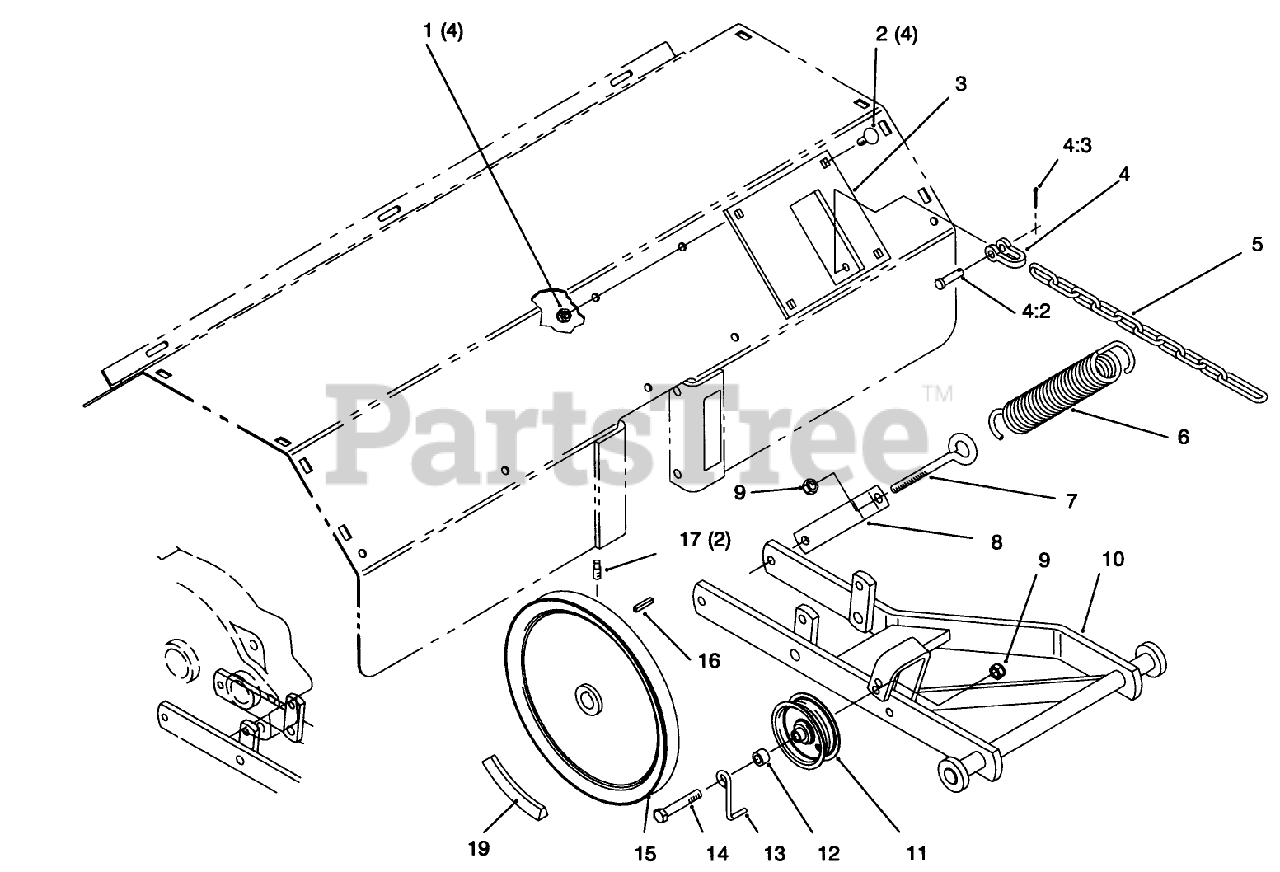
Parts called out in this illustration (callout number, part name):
1	NUT-LOCK, NI
2	BOLT-CARR
3	HITCH ASM
4	CLEVIS ASM
4:2	Clevis Pin
4:3	PIN-COTTER
5	CHAIN-LIFT
6	SPRING
7	EYEBOLT
8	BRACKET - SPRING RED
9	NUT-LOCK, NI
10	HITCH ASM RED
11	PULLEY-IDLER
12	Spacer
13	GUIDE-BELT
14	SCREW-HH
15	PULLEY
16	KEY-STRAIGHT
17	SCREW-SQH
19	DECAL-BELT ROUTING
